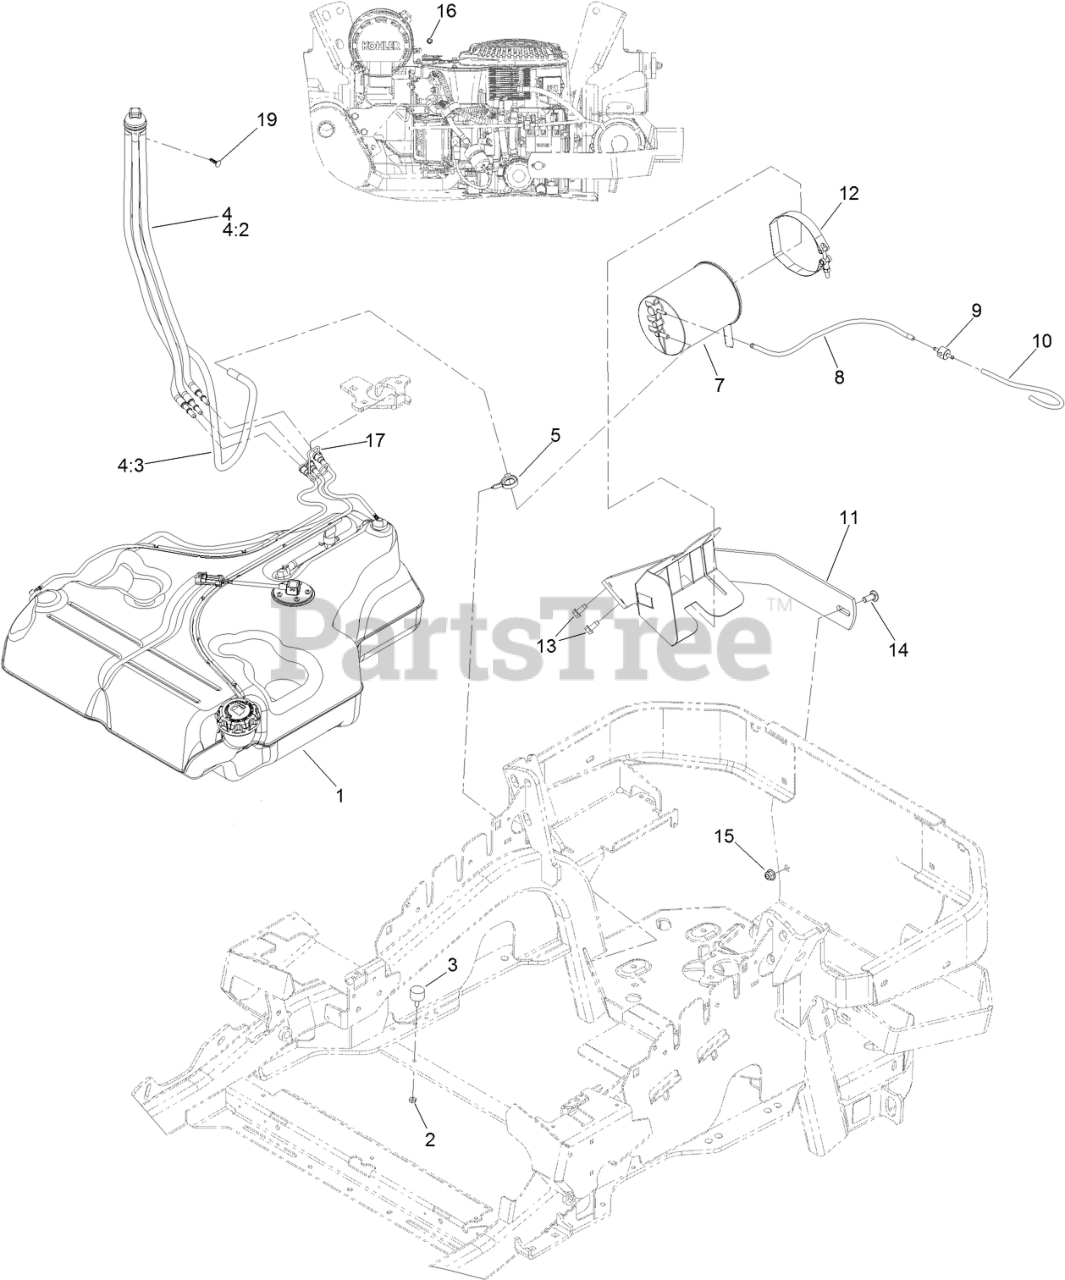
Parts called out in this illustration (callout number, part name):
1	FUEL TANK ASM
2	NUT-JAM
3	BUMPER
4	FUEL MANIFOLD VENT ASM
4:2	HOSE-FUEL
4:3	HOSE-FUEL
5	CLAMP-HOSE
7	CANISTER-CARBON, 1200CC
8	HOSE-VENT, FORMED
9	VALVE-CHECK, VACUUM
10	HOSE-VENT, FORMED
11	MOUNT-CANISTER
12	CLAMP, T-BOLT
13	SCREW-HWHTF
14	SCREW-CARR
15	NUT-HF, NI
16	PLUG-PORT
17	RETAINER-LINE, VAPOR
19	PLUG-PLASTIC
